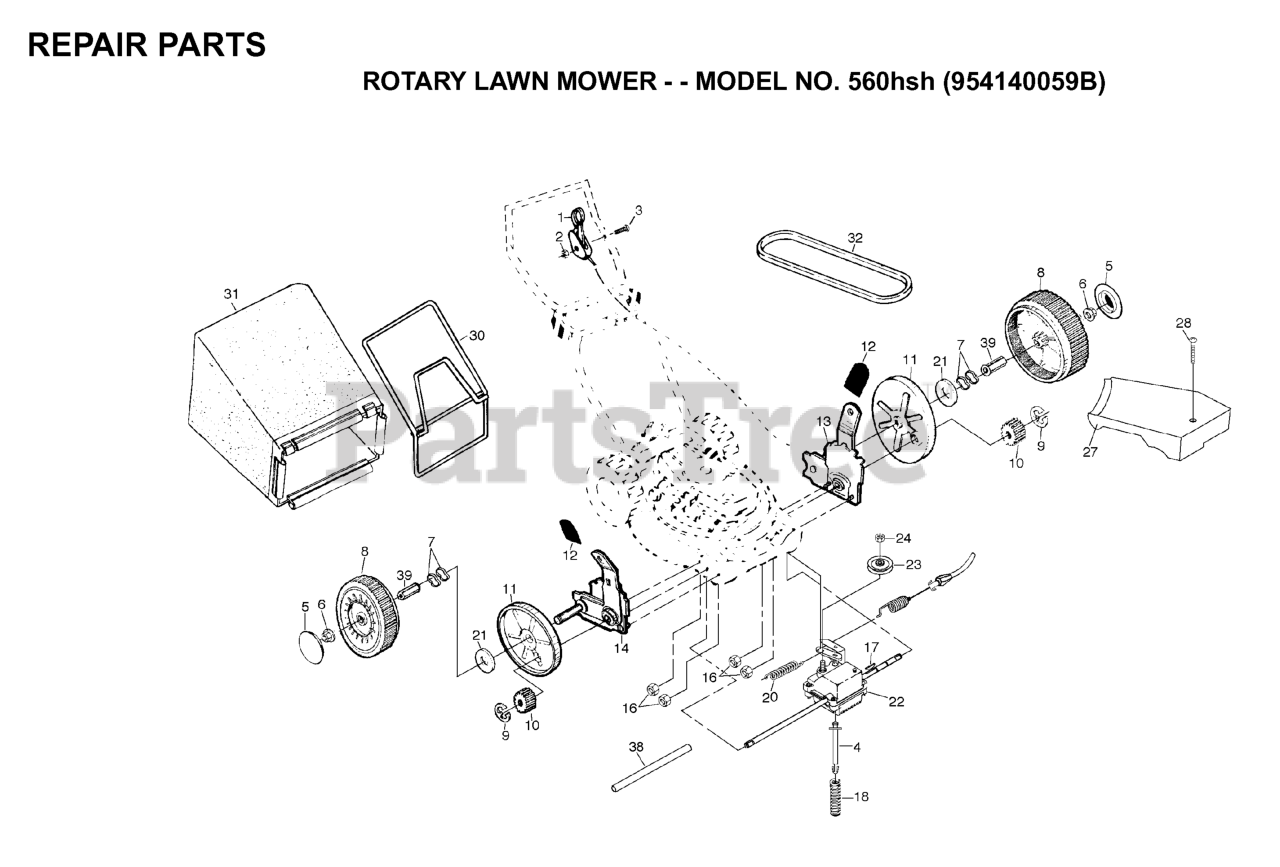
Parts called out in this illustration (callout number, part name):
1	DRIVE CONTROL
2	LOCK NUT
3	SCREW.PAN.HEAD
4	SPRING RETAINER
5	HUBCAP.8".GREY
6	HEX FLANGE LOCKNT
7	WAVE WASHER
8	WHEEL & TIRE 8 X 2
9	E-RING 7/16 RE
10	PINION GEAR
11	DUST SHROUD PM
12	SELECTOR KNOB
13	WHEEL ADJUSTER ASSY (LEFT)
14	WHEEL ADJUSTER KIT RH
16	NUT
18	SPRING.EXTENSION
21	WASHER FLUT
22	GEAR CASE ASMBLY
23	PULLEY
24	FLANGED LOCKNUT 3/8-16 ZINC
28	Screw, Tapping, Pan Head #10-24 x 2-3/4
30	CATCHER.FRAME.WALK
31	GRASS BAG
32	BELT THERM .32
38	DRV SHAFT TUBE PM
39	BUSHING PM
